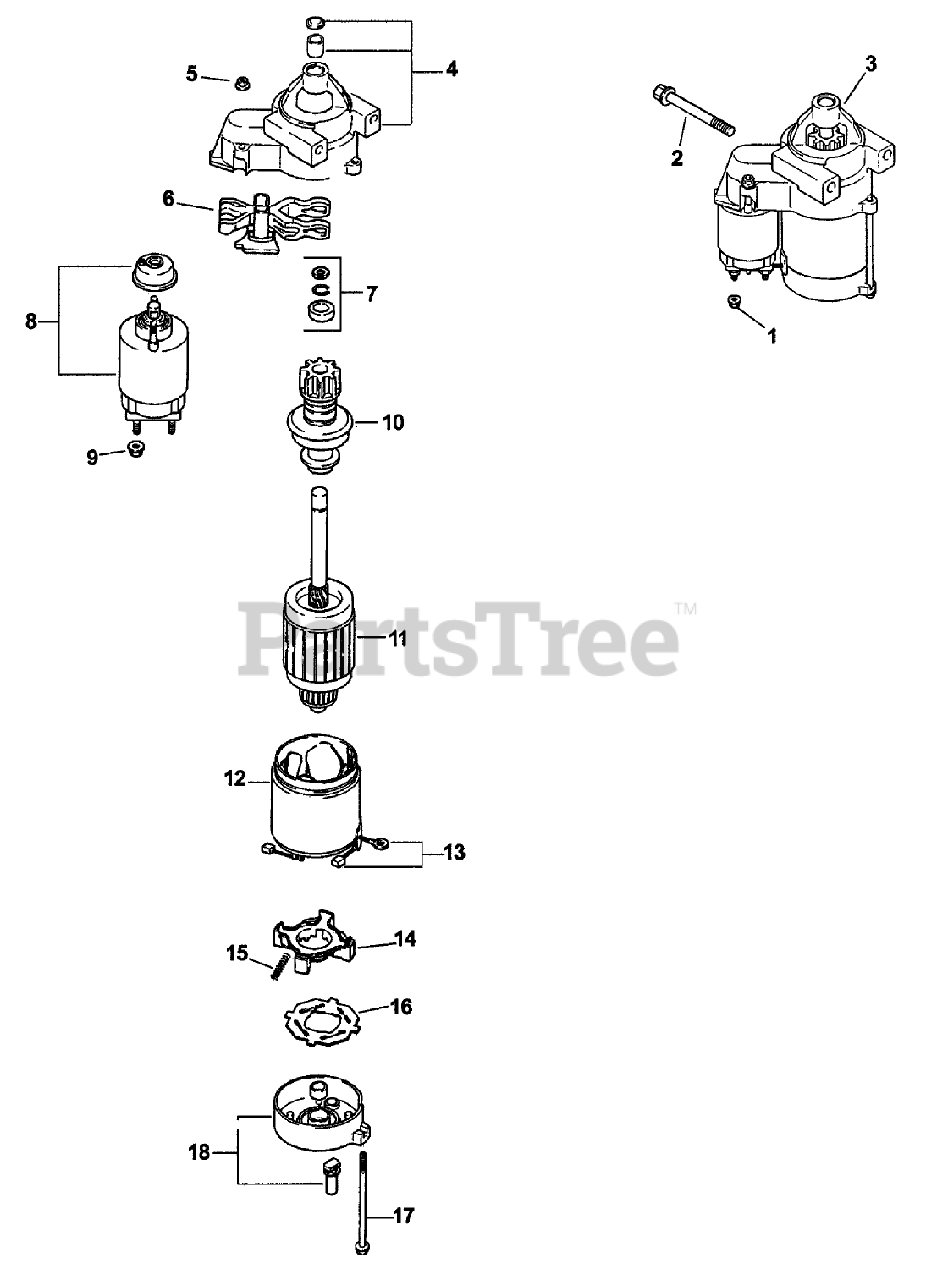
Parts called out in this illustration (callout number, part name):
1	Nut
2	Screw, hex. flange
3	Starter, solenoid shift (Includes 4-18)
4	CAP-END, DRIVE
5	Nut-Starter
6	LEVER-DRIVE, STARTER
7	STARTER REPAIR KIT
8	Solenoid
9	Nut
10	Drive-Pinion
11	Armature-Starter
12	Frame w/Brushes ASM
13	Kit, brush (Includes 15)
14	Holder-Brush
15	Spring-Brush
16	Insulator
17	Bolt-Thru
18	CAP-END, COMMUTATOR
